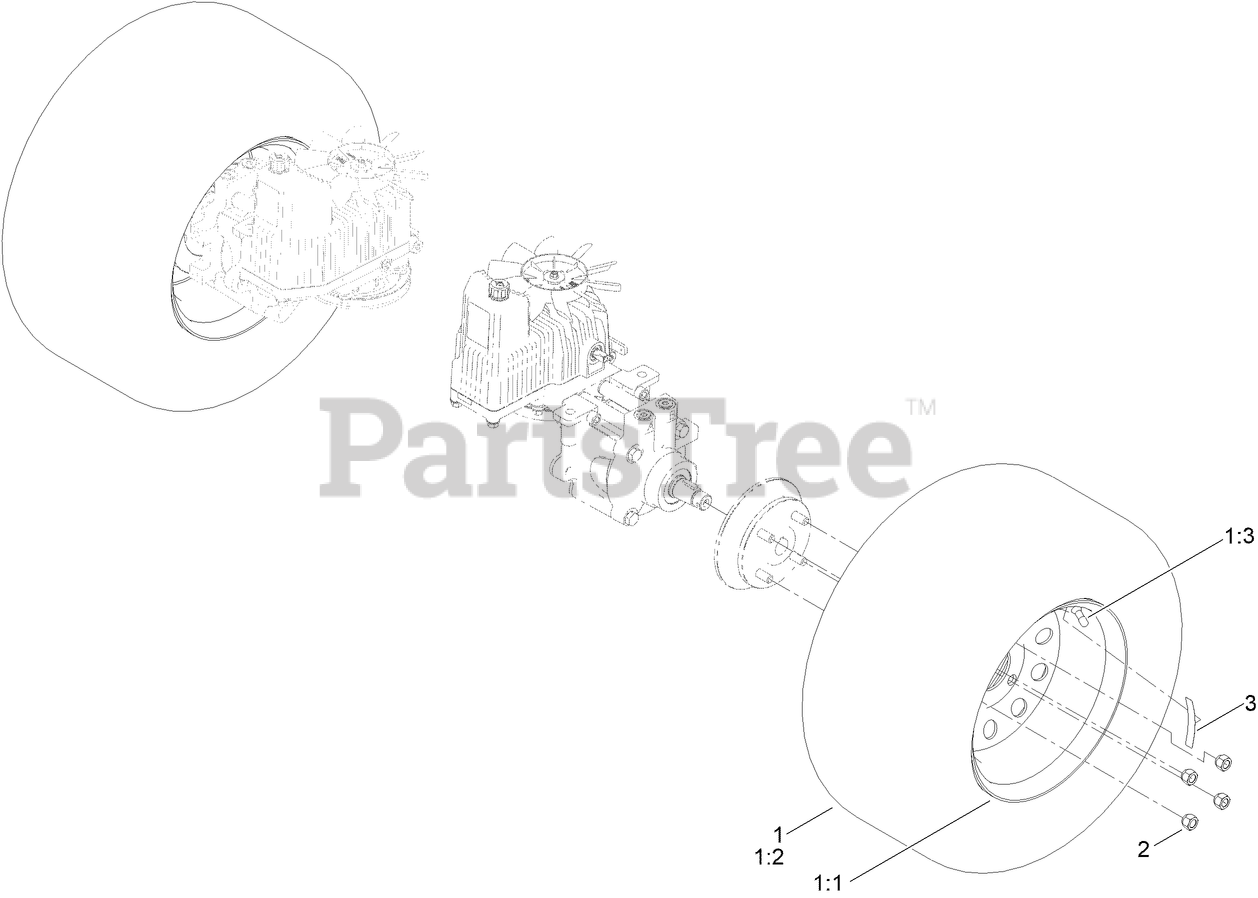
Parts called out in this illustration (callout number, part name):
1	WHEEL AND TIRE ASM
2	NUT-LUG
3	DECAL-TORQUE, WHEEL HUB LUG
